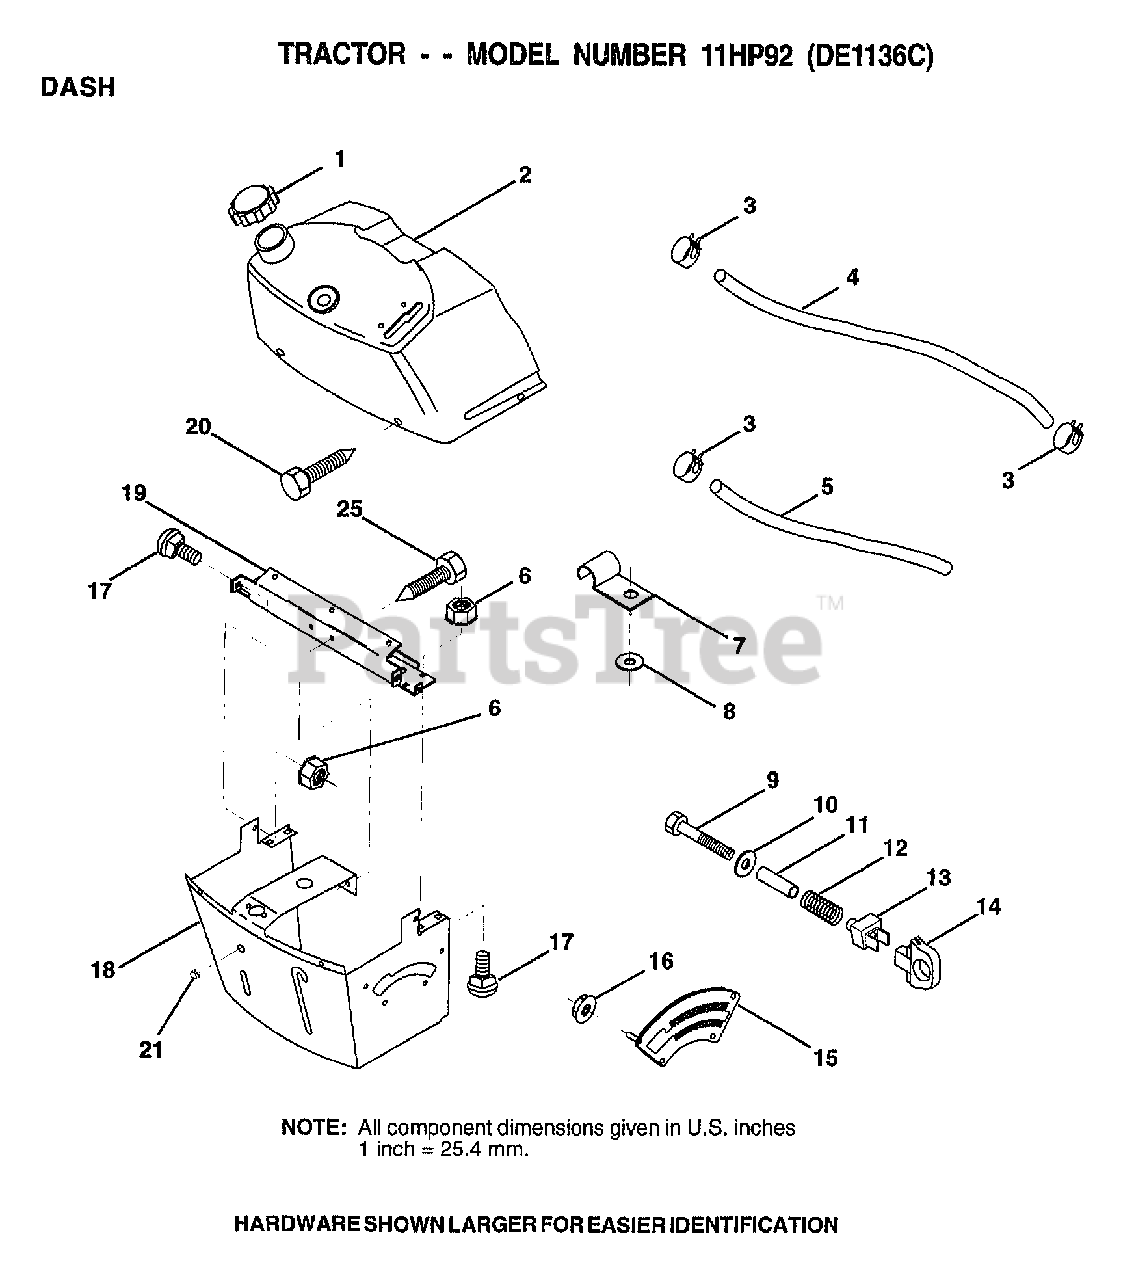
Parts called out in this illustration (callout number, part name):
1	CAP BLK FUEL LR
2	TANK.ASM.DASH.LR
3	HOSE CLAMP
5	FUEL LINE T
6	NUT HXKEP 1/4X20
7	CLIP T
8	WASHER PM
9	BOLT
11	SPACER SPLIT
12	SPRING M
13	"KNOB,HGT RETAINER"
14	KNOB
15	ADJUSTER QUAD
16	NUT
17	BOLT
18	SUPT ASSY DASH
19	CROSS BRACE
20	SCREW.1/4-20X1/2
21	PLUG DOME
25	SCREW LT
